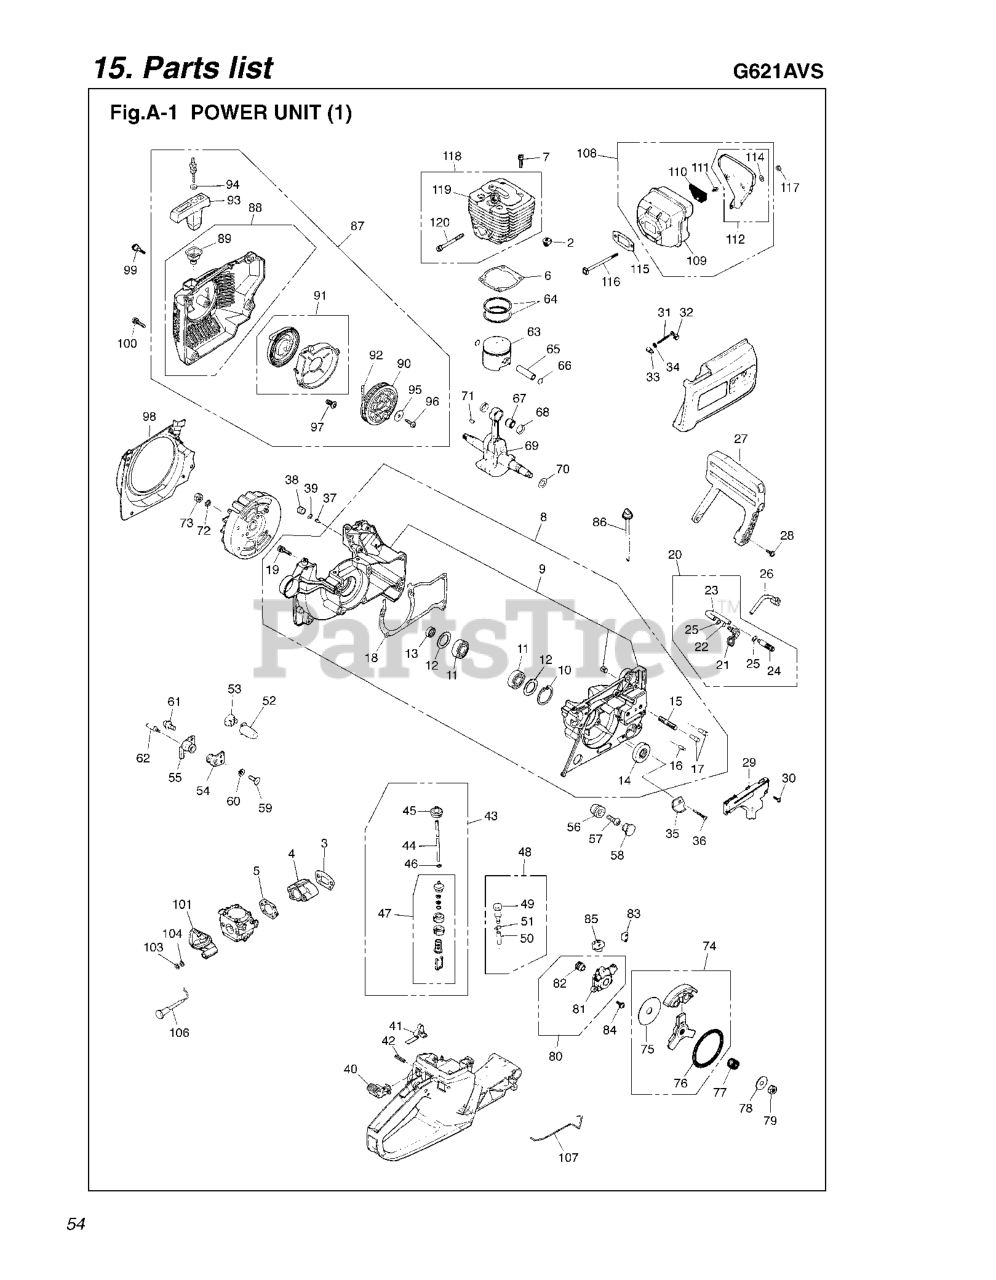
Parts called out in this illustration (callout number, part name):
3	GASKET, INS. (R-26161411-12)
4	INSULATOR
5	GASKET, CARB (RPLS 261814131)
8	CRANKCASE-ASSY(RPLS2616-21001)
9	CRANKCASE (RP261621100,1101)
10	SNAP RING
15	STUD BOLT
18	GASKET (RPLS 3356-21310)
20	OIL PIPE COMP
21	PIPE.OIL
26	PIPE.OIL
27	%GUARD (RPLS 262224310)
28	RP_SCREW
34	WASHER, M5 x .8
38	BREATHER SEAL
43	PIPE ASSEMBLY
46	CLIP
47	FILTER ASSY
48	BREATHER
49	BREATHER
51	CLIP
64	RING.PISTON
66	SNAP RING
69	CRANKSHAFT (RPLS42000-42003)
70	SHIM
71	KEY
74	CLUTCH ASSY (RPLS 261651200)
75	PLATE
80	OIL PUMP (R335655101&55102)
83	GASKET, PUMP
87	STARTER ASSY (RPLS75000-75003)
99	SCREW (RPLS 261675710)
101	MANIFOLD
103	WASHER, SPRING M4 x 1.3
104	WASHER, M5 x .8
106	ROD.CHOKE
108	MUFFLER ASSY (RPLS 335715102)
110	ARRESTER
112	MUFFLER GUARD SET
118	CYLINDER SET(RA7,261812114-16)
120	BOLT (RPLS 335682210-11)
